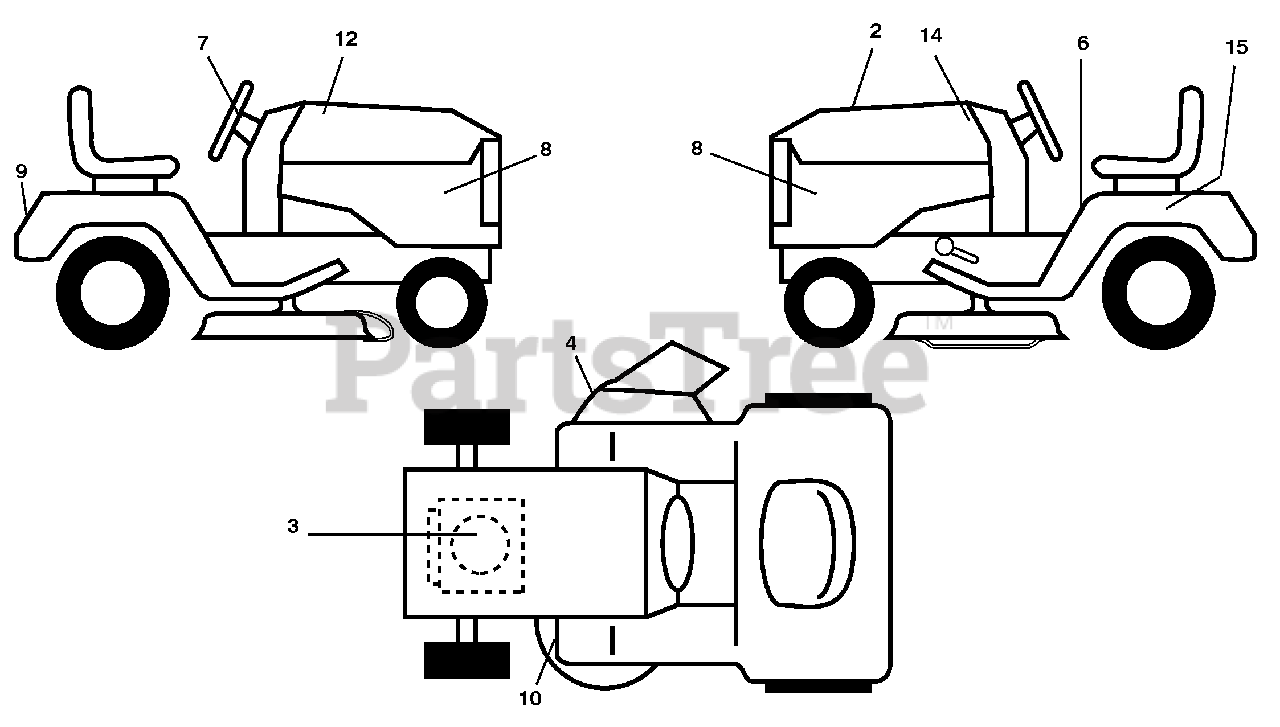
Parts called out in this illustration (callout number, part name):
2	Decal, Replacement
3	Decal, Engine HP
4	Decal Warning
6	Decal, Fender Warning (E&F)
7	Decal Ins Str Wh
8	Decal, Side Panel
9	Decal, Fender
10	Decal, V-Belt Sch.
12	Decal, Hood RH
14	Decal, Hood LH
15	Decal, Caution, Battery
15	Decal, Handle Lft Height Adj.
15	Manual, Operator's (E&F)
15	Manual, Parts (E&F)
